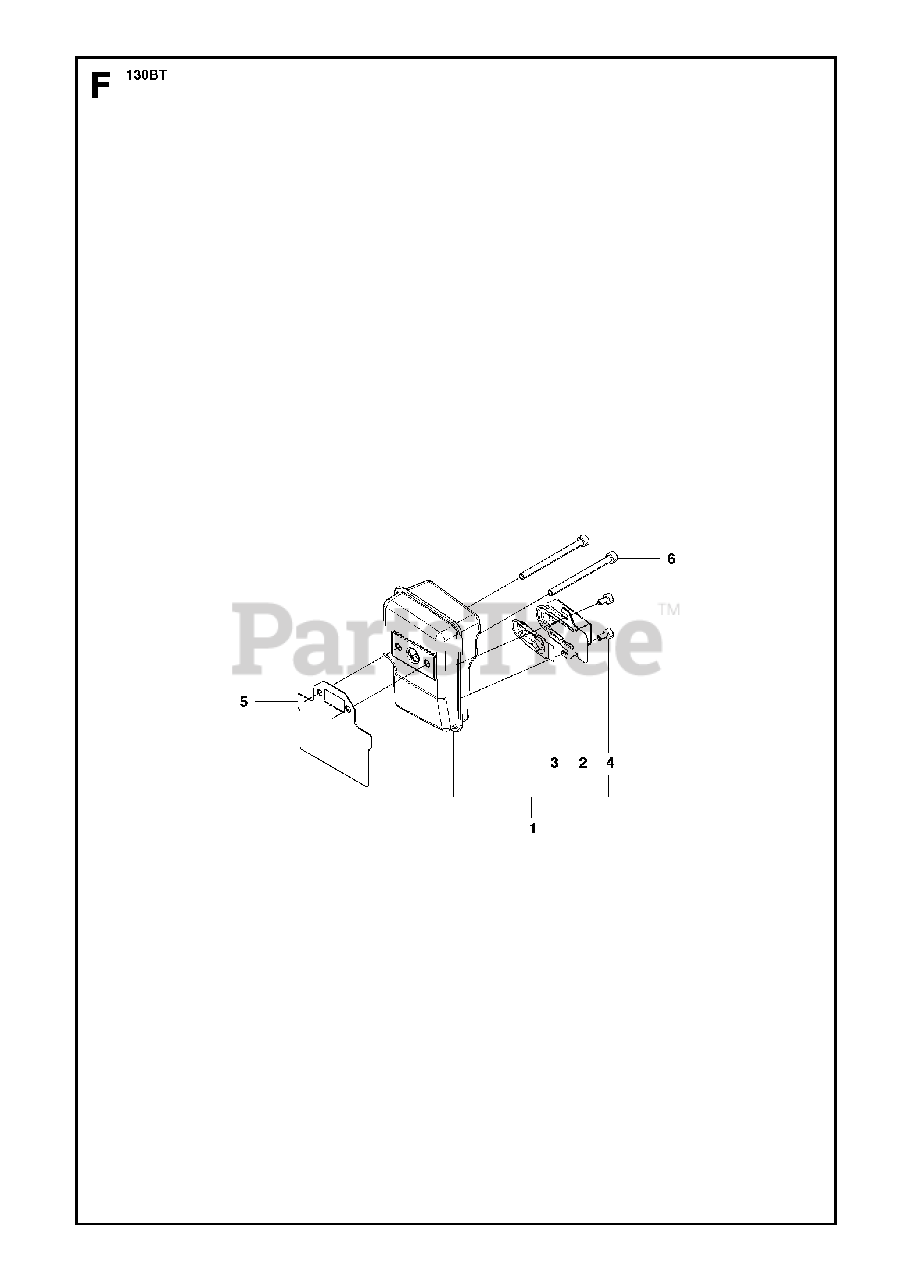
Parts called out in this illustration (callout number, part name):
2	EXHAUSE DUCT
3	ARRESTER
4	BOLT
